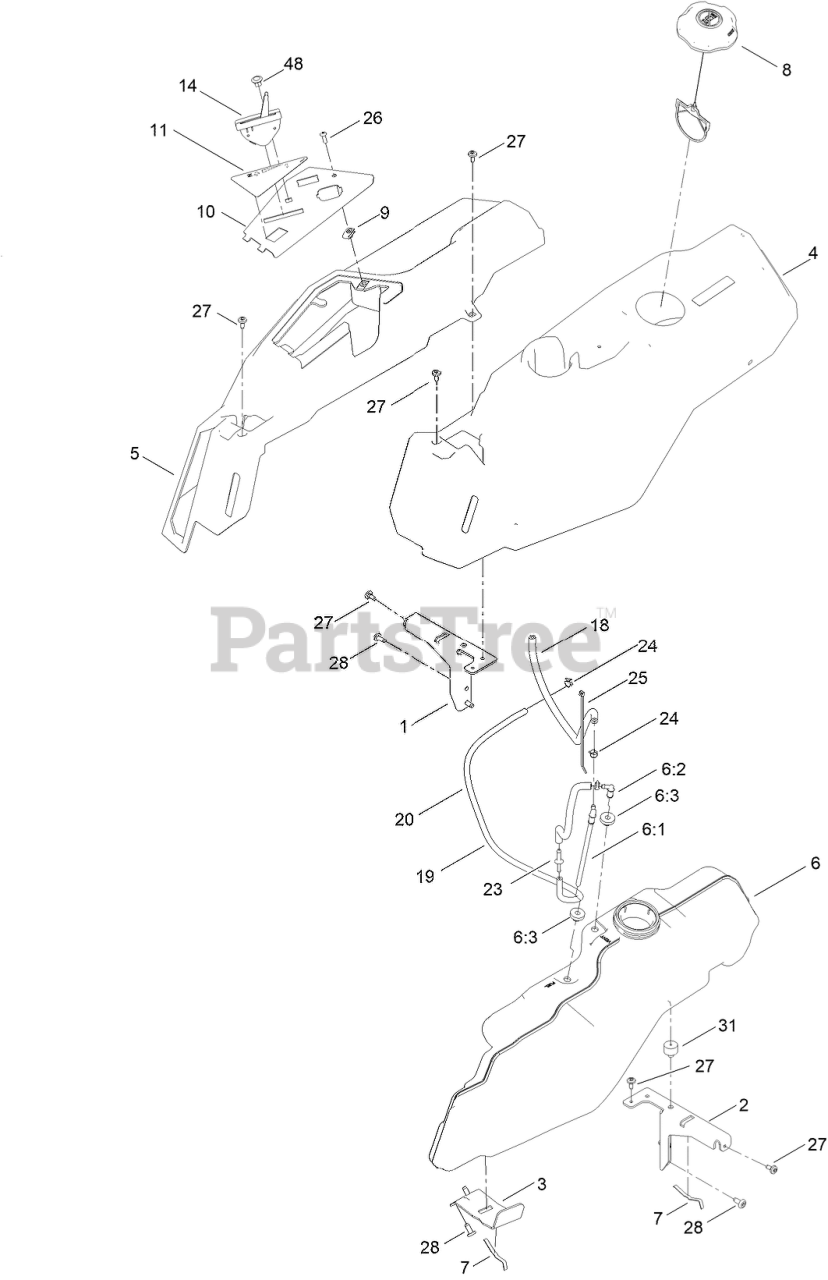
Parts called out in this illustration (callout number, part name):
1	SUPPORT-POD, RH
2	SUPPORT-POD, LH
3	SUPPORT-TANK, FUEL
4	POD-LH
5	POD-RH
6	FUEL TANK ASM
6:1	CONNECTOR-ELBOW, 90 DEG
6:2	FITTING-PLASTIC
6:3	BUSHING
7	SPRING
8	CAP-FUEL, RATCHETING
10	PANEL - CONTROL
11	DECAL-PANEL CONTROL
14	CABLE-THROTTLE AND CHOKE
18	HOSE-FUEL
19	HOSE-FUEL
20	HOSE-FUEL
23	ADAPTOR-ORIFICE
24	CLAMP-HOSE
25	TIE-CABLE
26	SCREW-PRH
27	SCREW-SHOULDER
31	BUMPER-GROMMET
48	PLUG-DASH
